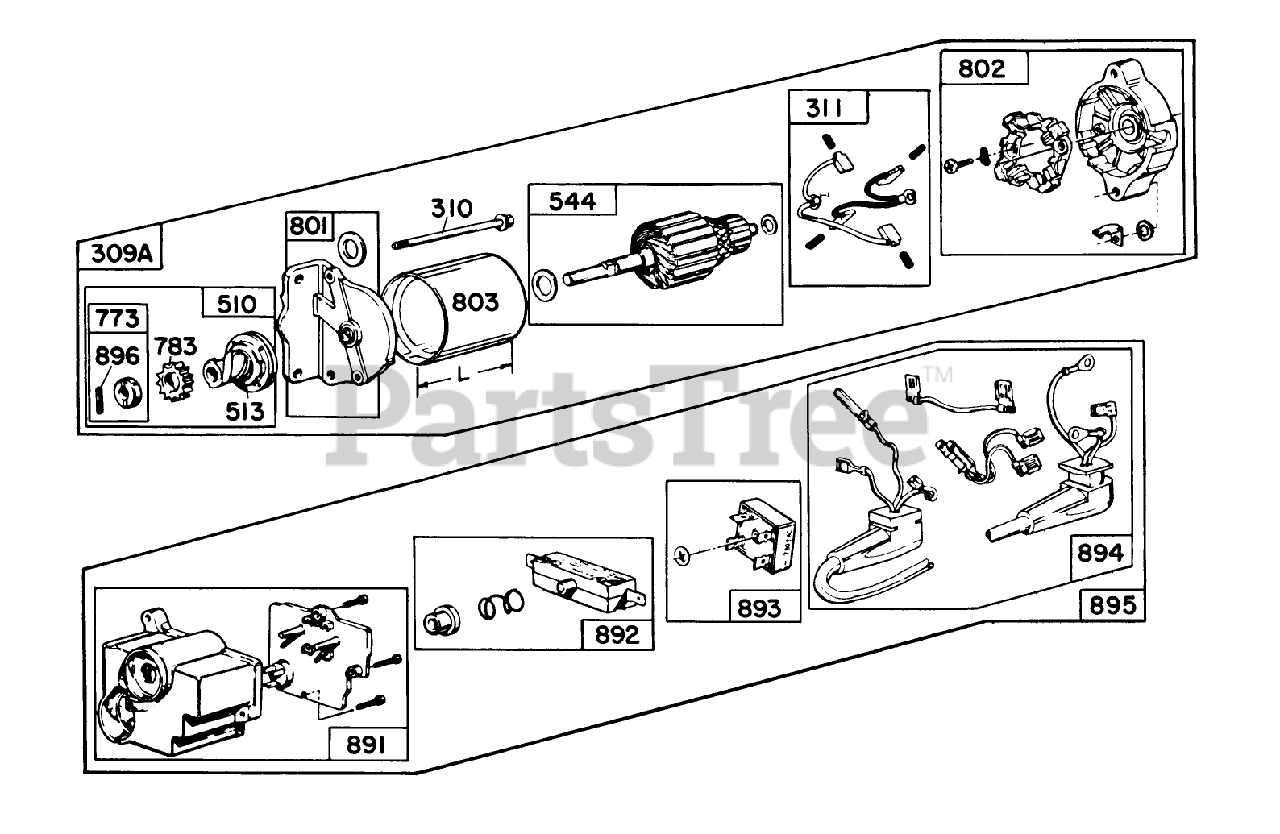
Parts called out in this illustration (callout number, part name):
309	Motor Drive Assembly
310	Thru Bolt Assembly
311	Brush Assembly
510	Drive Assembly
513	Clutch Assembly
544	Armature Assembly
773	Gear-Starter
801	Drive End Cap Assembly
802	Comm. End Cap Assembly
803	Housing Assembly
891	Housing Group
892	Switch Group
893	Rectifier
894	Lead Group
895	Control Group
